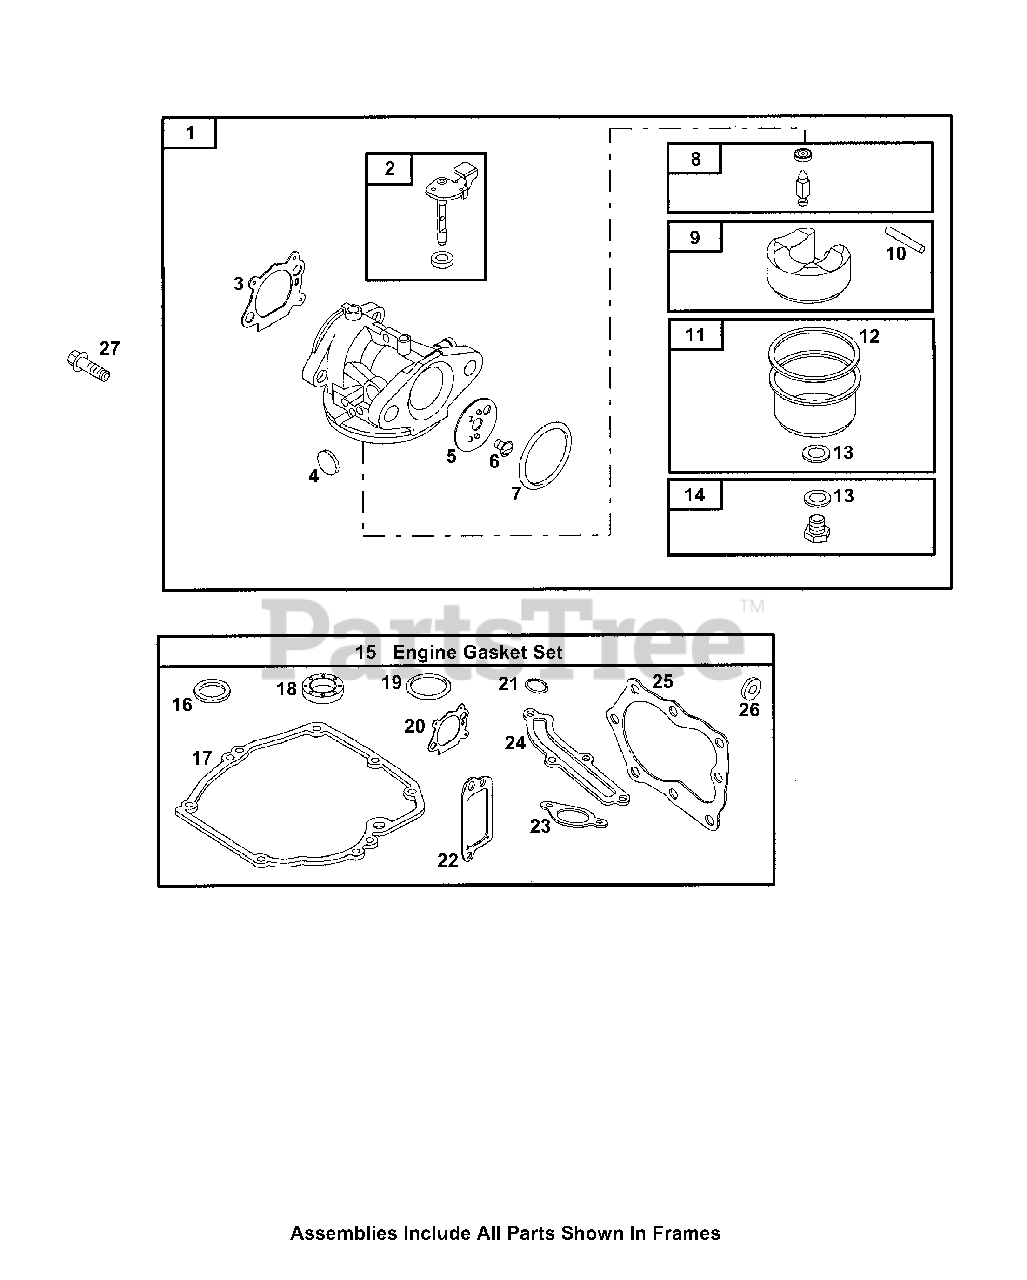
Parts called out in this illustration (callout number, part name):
1	Carburetor
2	Throttle Shaft
3	Air Cleaner Gasket
4	Welch Plug
5	Throttle Valve
6	Screw (Throttle Valve)
7	O-Ring Seal (Intake Manifold)
8	Needle/Seat Kit
9	Carburetor Float
10	Float Hinge Pin
11	Float Bowl
12	Float Bowl Gasket
13	Sealing Washer
14	Main Jet
15	Engine Gasket Set
16	Oil Seal
17	Crankcase Gasket
18	Oil Seal
19	Dipstick/Tube Seal
20	Air Cleaner Gasket
21	Dipstick Tube Seal
22	Breather Gasket
23	Intake Gasket
24	Breather Passage Gasket
25	Cylinder Head Gasket
26	Spacer
27	Screw (Carburetor)
